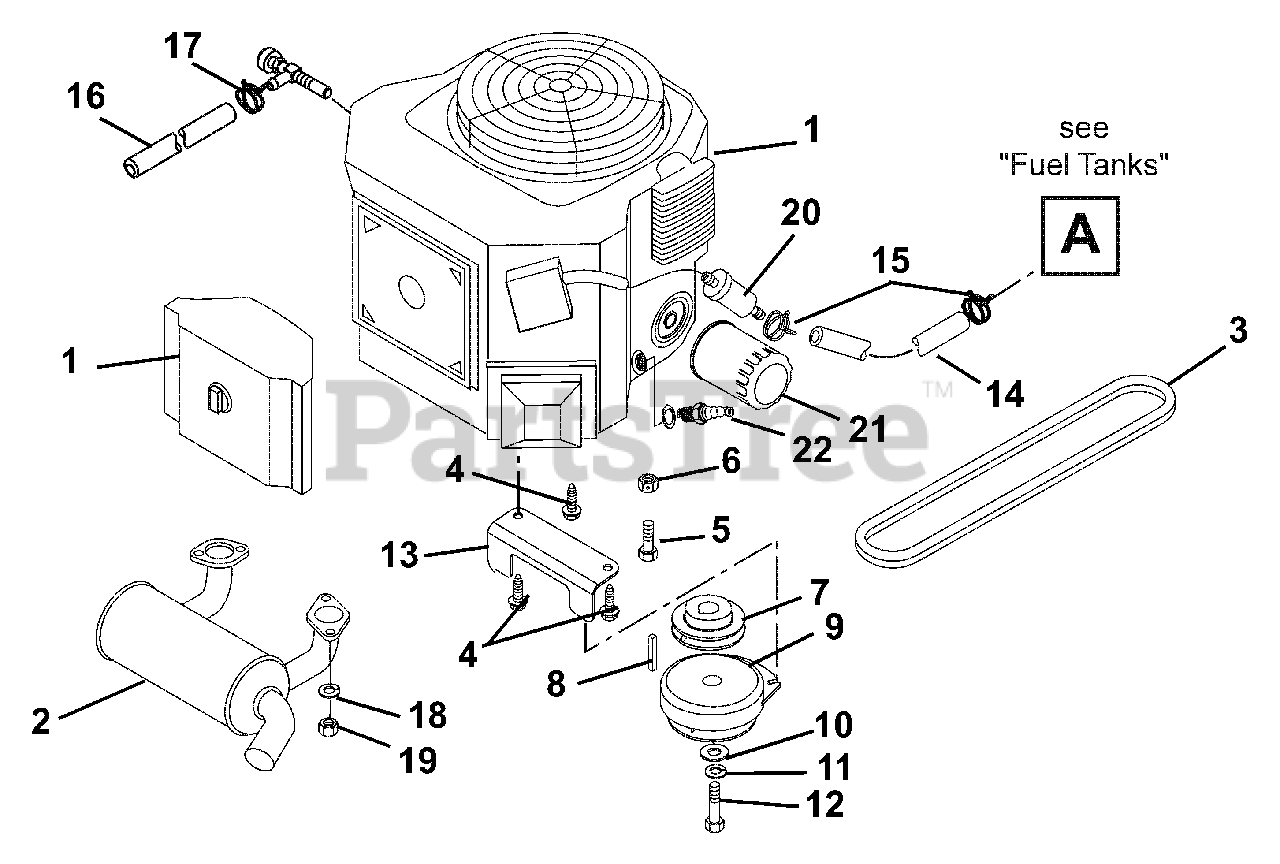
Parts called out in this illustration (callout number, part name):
1	ENGINE, 15HP KAW FH451V
2	MUFFLER, KAW. (COMPACT-Z)
3	V-BELT, HA-RAW EDGE
4	@SCR-TAP .38-16X1.00 HWH TR YZ
5	@BLT-HEX .31-18X1.50 GR5 YWZC
6	@NUT-LK-TOP-FLG .31-18 YWZC
7	PLY-V 4.OO X 1.00
8	KEY-SQ .25X.625X.25 SAE 8630
9	CLUTCH, ELECTRIC
10	WSHR-FL-STL .469X2.00X.25 YWZC
11	@WSHR-LK .44X.109 REG YWZC
12	BLT-HEX .44-20X2.50 GR5 YWZC
13	BRACKET, CLUTCH
14	HOSE, 35"-1/4"ID GAS LINE
15	CLAMP-HOSE WIRE .490/.510X.116
16	HOSE, 1/2 X 6.00
17	CLAMP,.88 DIA. HOSE
18	@WSHR-LK .31X.078 REG YWZC
19	NUT-HEX M8-1.25 YWZC
20	FILTER, FUEL - KOH CV20
21	FILTER,OIL - KAW
22	PLUG, SPARK
